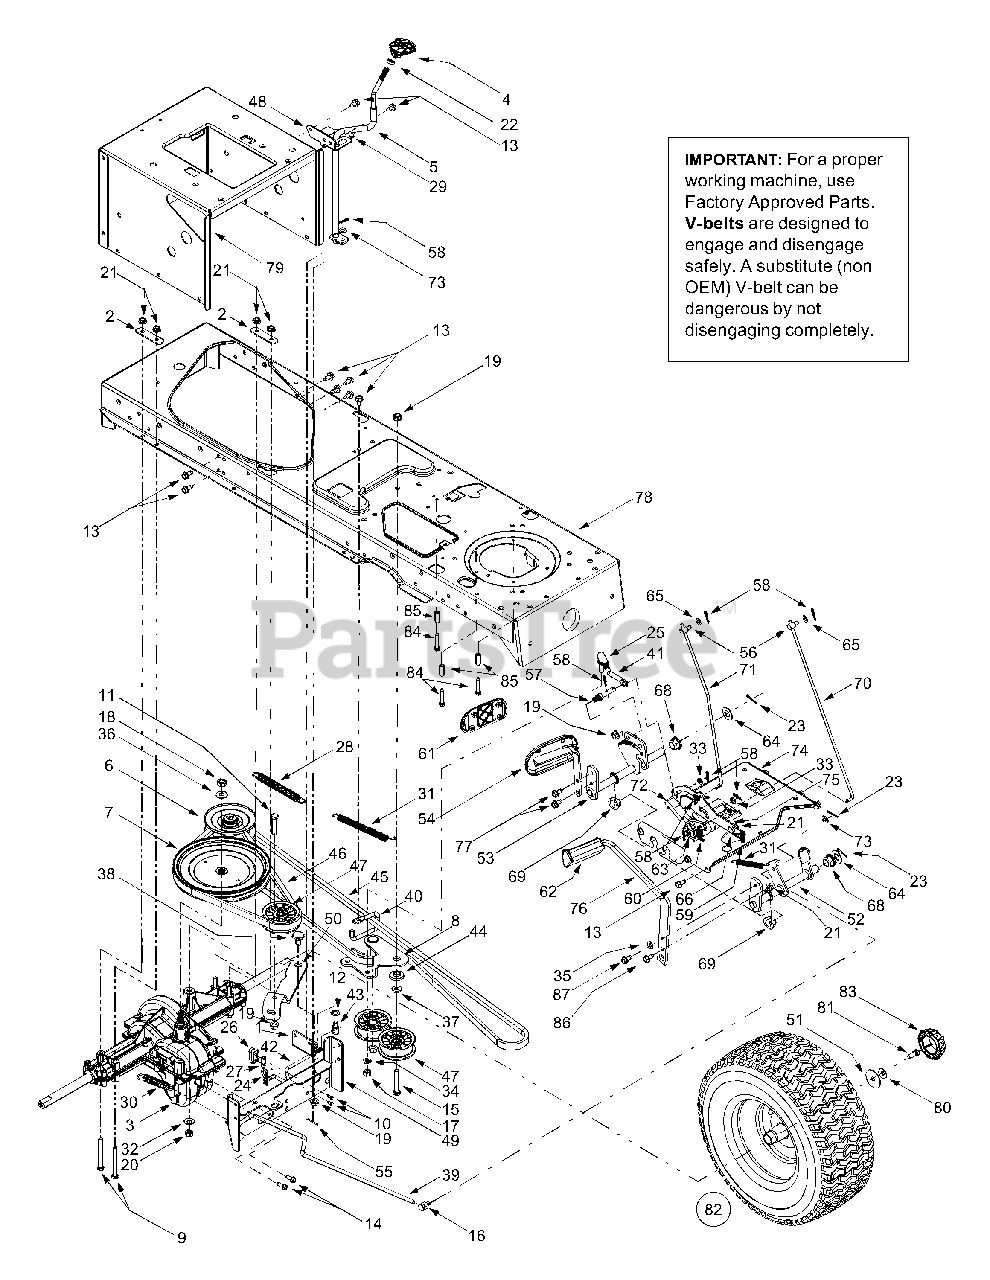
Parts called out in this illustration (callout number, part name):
1	Shift Lever Support
2	Transaxle Mounting Bracket
3	Single-speed Transmission Assembly
4	Shifter Knob
5	Shift Lever
6	Variable-speed Pulley Assembly
7	Transmission Pulley, 8.5 x .5-36
8	Double-idler Bracket
9	Hex Cap Screw, 5/16-18 x 2.75
10	Self-tapping Screw, #8-18 x .5
11	Hex Cap Screw, 3/8-16 x 1.75
12	Flat Washer, .51 x 1.0 x .060
13	Self-tapping Screw, 5/16-18 x .625
14	Self-tapping Screw, 1/4-20 x .75
15	Hex Cap Screw, 3/8-16 x 2.25
16	Ferrule, 5/16-18
17	Hex Nut, 3/8-24
18	Hex Nut, 7/16-20
19	Flange Lock Nut, 3/8-16
20	Hex Nut, 3/8-16
21	Flange Lock Nut, 5/16-18
22	Jam Nut, 3/8-16
23	Cotter Pin
24	Internal Cotter Pin
25	Ball Joint
26	Short Spring Switch
27	Insulator Nut Plate
28	Extension Spring, .62 Dia. x 6.12
29	Compression Spring Clip
30	Extension Spring, .59 OD x 4
31	Extension Spring, .50 Dia. x 6.37
32	Bell Washer, .401 x .87 x .063
33	Flat Washer, .385 x .62 x .063
34	Lock Washer, 3/8
35	Flat Washer, .344 x .750 x .120
36	Bell Washer, .45 x 1.0 x .602
37	Flat Washer, .407 x .812 x .135
38	Shoulder Screw, .625 x .217
39	Brake Rod
40	Belt Guard
41	Idler Adjustment Rod, 3/8
42	Shift Rod
43	Adjustment Ferrule, 1/4-20 x 1.0
44	Shoulder Spacer, .38 ID
45	Lower Drive Belt
46	Upper Drive Belt
47	Flat Idler, 2.75 OD
48	Speed Control Rod Bracket
49	Transmission Torque Bracket
50	Idler Bracket
51	Flat Washer, .350 x 1.59 x .062
52	Brake Control Assembly
53	Speed Control Assembly
54	Drive Pedal Assembly
55	Cotter Pin, 1/8 x 1.25
56	Ferrule, 1/4-20
57	Pin, 3/8-16 x 2.43
58	Cotter Pin
59	Compression Spring, .34 OD x 1.0
60	Extension Spring, .50 OD x 1.41
61	Drive Pedal Pad
62	Brake Pedal Pad
63	Flat Washer, .281 x .5 x .063
64	Flat Washer, .64 x 1.24 x .06
65	Flat Washer, .344 x .062 x .03
66	Shoulder Screw, .437 x 1.62
68	Hex Flange Bearing
69	Split Hex Flange Bearing
70	Cruise Control Rod
71	Brake Lock Control Rod
72	Cruise Latch
73	Flat Washer, .344 x .688 x .065
74	Steering Support Bracket
75	Drive Lockout Bracket
76	Brake Pedal
77	Self-tapping Screw, 5/16-18 x .75
78	Lower Frame Assembly
79	Hitch Plate
80	Bell Washer, .34 x .872
81	Hex Cap Screw, 5/16-24 x .75
82	Wheel Assembly Complete 20 x 8 x 8 Square Shoulder
83	Deluxe Hub Cap
84	Self-tapping Screw, 1/4-20 x 1.25
85	Spacer
86	Self-tapping Screw, 5/16-18 x .875
87	Self-tapping Screw, 5/16-18 x .75
